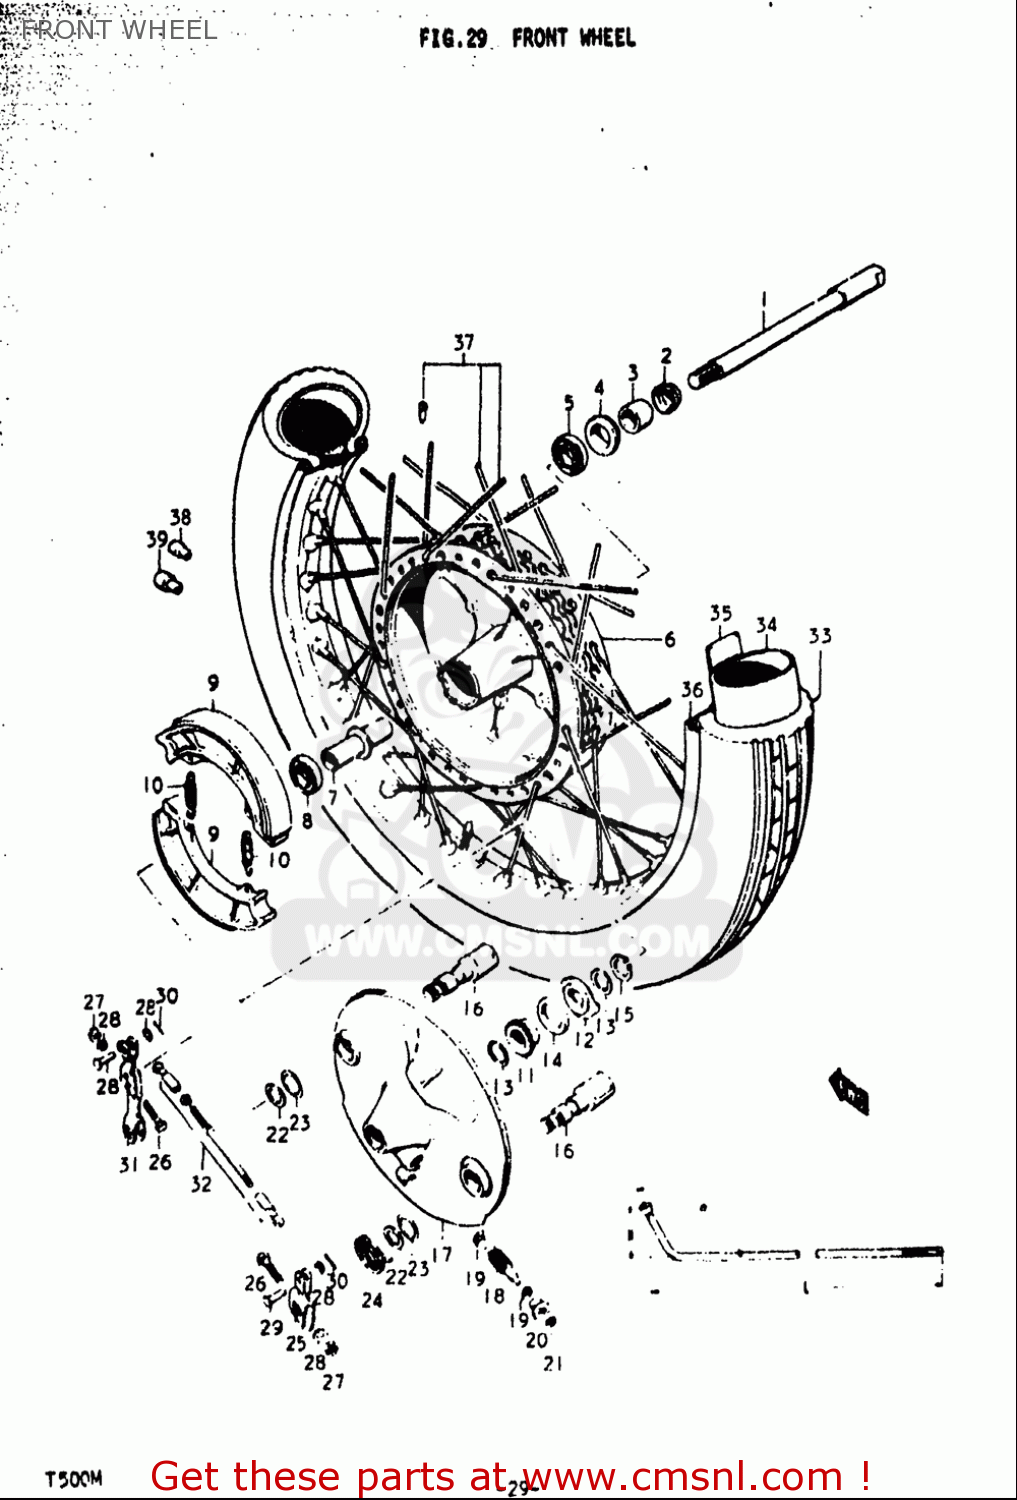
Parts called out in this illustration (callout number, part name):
1	AXLE,FRONT
3	SPACER
5	BEARING
7	SPACER,FRONT HUB BEARING
8	BEARING
9	SHOE SET,BRAKE (NAS)
10	SPRING,BRAKE SHOE
12	DRIVER,SPEEDOMETER GEAR
13	WASHER(22.5X27X1)
14	SEAL,OIL(26X38X4)
15	CIRCLIP
16	CAM,RR BRAKE
18	PINION,SPEEDOMETER
19	WASHER(5.1X9X0.4)
20	BUSHING,SPEEDOMETER PINION
21	SEAL,OIL(6X10X3)
22	WASHER(15.5X24X1.6)
23	O RING(D:2.4,ID:14.8)
24	SPRING
26	BOLT(6X31)
27	NUT
28	WASHER
30	PIN 12X10
34	TUBE ASSEMBLY,WHEEL,INNER
35	PROTECTOR,WHL INR TUBE
36	RIM,WHEEL
